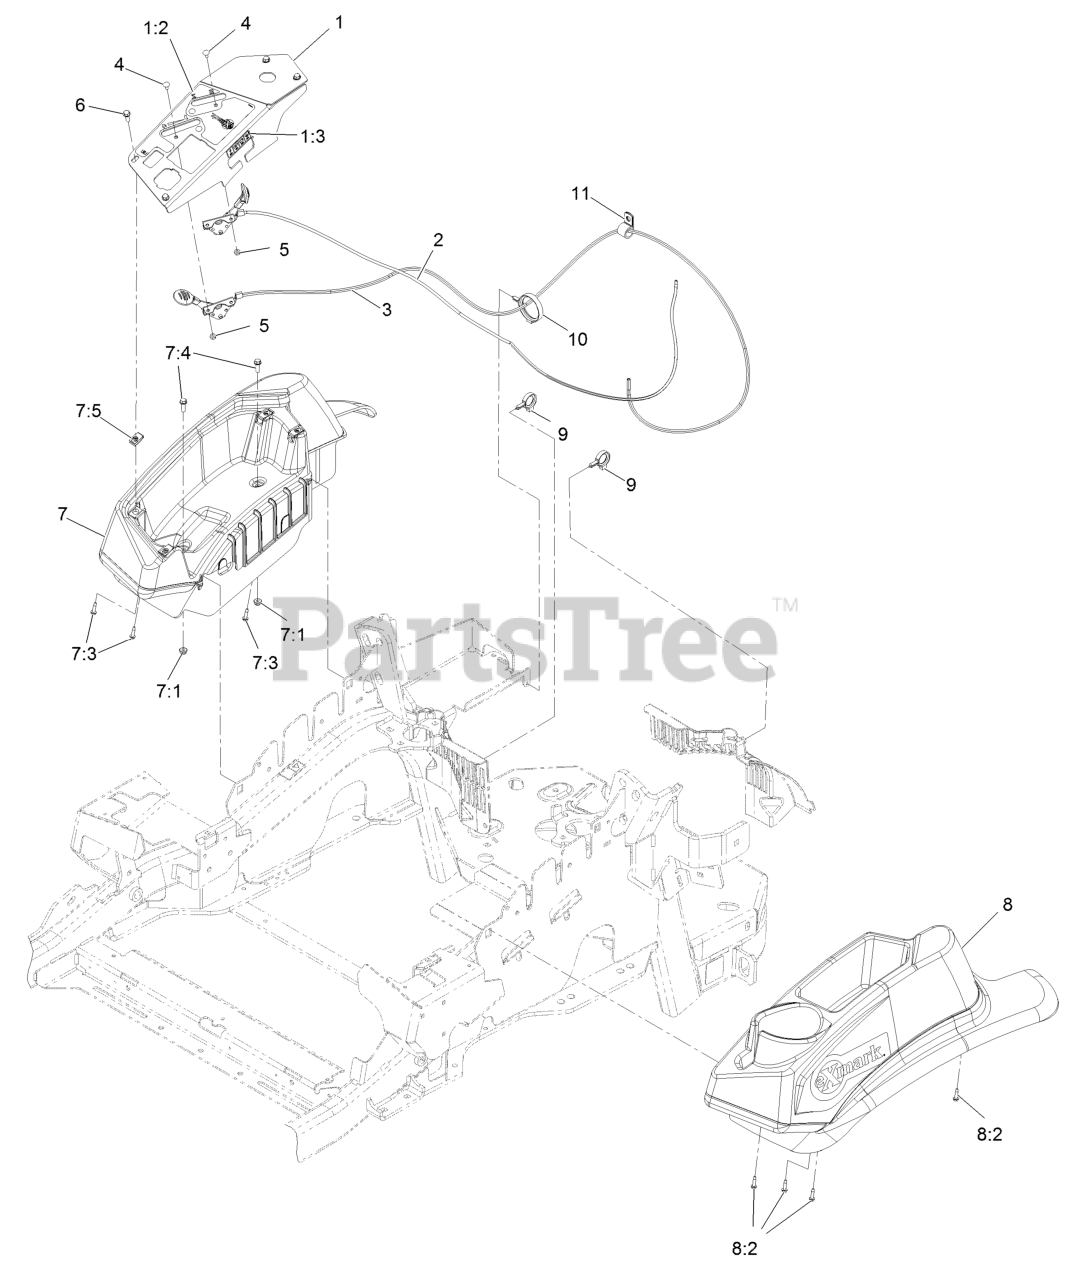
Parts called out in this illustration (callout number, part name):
1	CONSOLE,PANEL W/DECAL
1:2	DECAL-CONTROL PANEL NON-E
1:3	DECAL-FUSES
2	ASM,CHOKE CABLE
3	ASM,THROTTLE CABLE
4	BOLT-CARR
5	NUT-LOCK, NI
6	SCREW-HWH
7	CONSOLE,RH NARROW ASM
7:3	SCREW,THD FORM,HWH
7:4	SCREW-HWH
7:5	Nut-Retainer-Panel 1/4-20
8	CONSOLE.LH NARROW ASM
8:2	SCREW,THD FORM,HWH
9	CLAMP-HOSE
10	CLAMP-HARNESS
11	CLIP-LOOM
